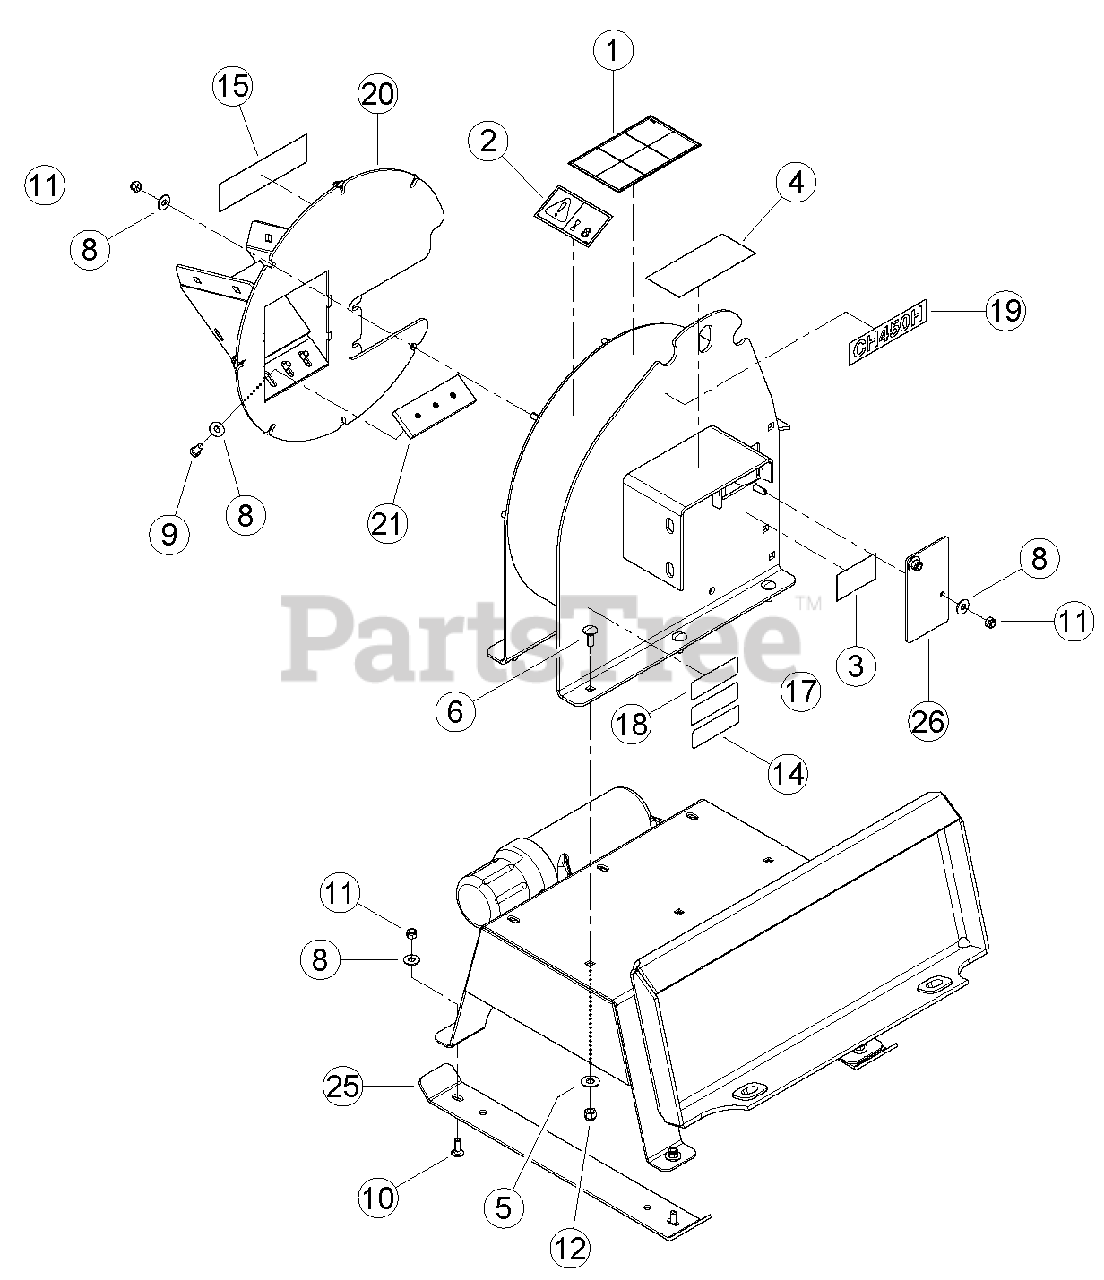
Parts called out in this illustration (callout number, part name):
1	DECAL, OPERATING INSTRUCTIONS ISO
2	DECAL, MAINTENANCE ISO
3	DECAL, DANGER
4	DECAL, MUTILINGUAL MANUAL
5	WASHER, 3/8 FLAT ZP
6	BOLT, 3/8 X 1 CRG GR5 NC ZP
7	BOLT, 3/8 X 5 HEX HD GR5 ZP
8	WASHER, 5/16 FLAT ZP
9	BOLT, 5/16 X 5/8 HEX HD GR5 ZP
10	BOLT, 5/16 X 7/8 CRG GR5 NC ZP
11	NUT, 5/16 NE NYLOCK ZP
12	NUT, 3/8 NE NYLOCK ZP
13	BOLT, 5/16 X 7/8 HEX HD NC GR5 ZP
14	DECAL, SERIAL NUMBER
15	DECAL, ECHO BEARCAT 6.82 X 1.90
16	CONTAINER, MANUAL
17	DECAL, ATLANTIC BRIDGE LTD INFO
18	DECAL, CH450H INFORMATION
19	DECAL, MODEL CH450H
20	WELDMENT, DISK COVER
21	ANVIL, CHIPPER
22	WELDMENT, CHIP DEFLECTOR
23	WELDMENT, CHIPPER HOUSING
24	WELDMENT, BASE
25	PLATE, BASE SKID
26	PLATE, ACCESS
